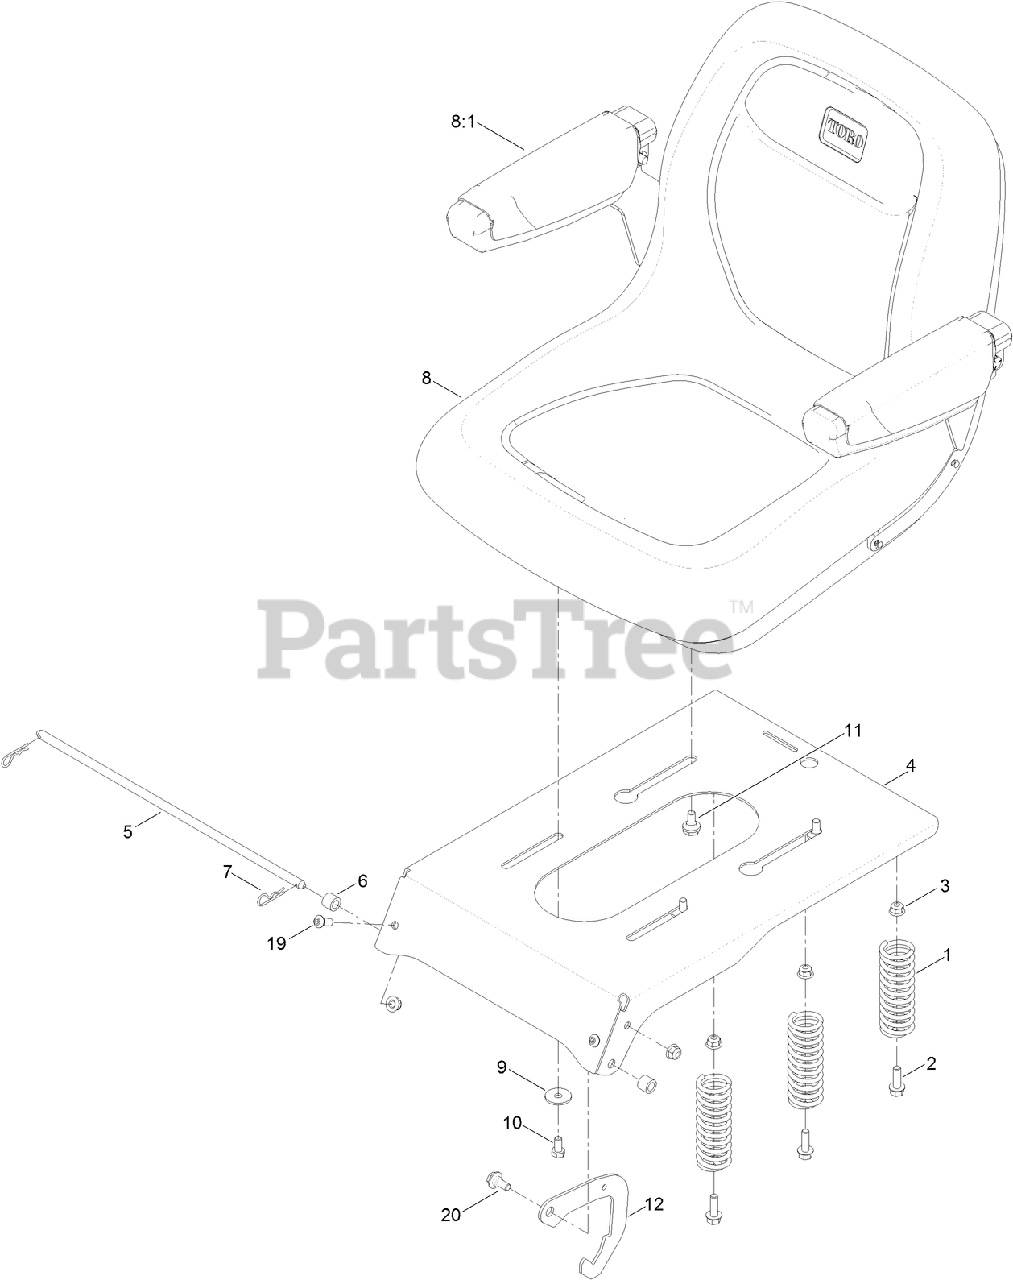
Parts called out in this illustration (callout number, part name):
1	SPRING-COMPRESSION
2	SCREW-HHF
3	NUT-HF, NI
4	PAN-SEAT
5	ROD-STOP
6	BUSHING-LEVER, LIFT
7	PIN-COTTER
8	SEAT-18 INCH
8:1	ARMREST KIT (MILSCO)
9	WASHER-PIVOT
10	SCREW-HH
11	BOLT-SHOULDER,HFH
12	LATCH-SEAT
19	SCREW-HSBH
20	SCREW-SHOULDER
